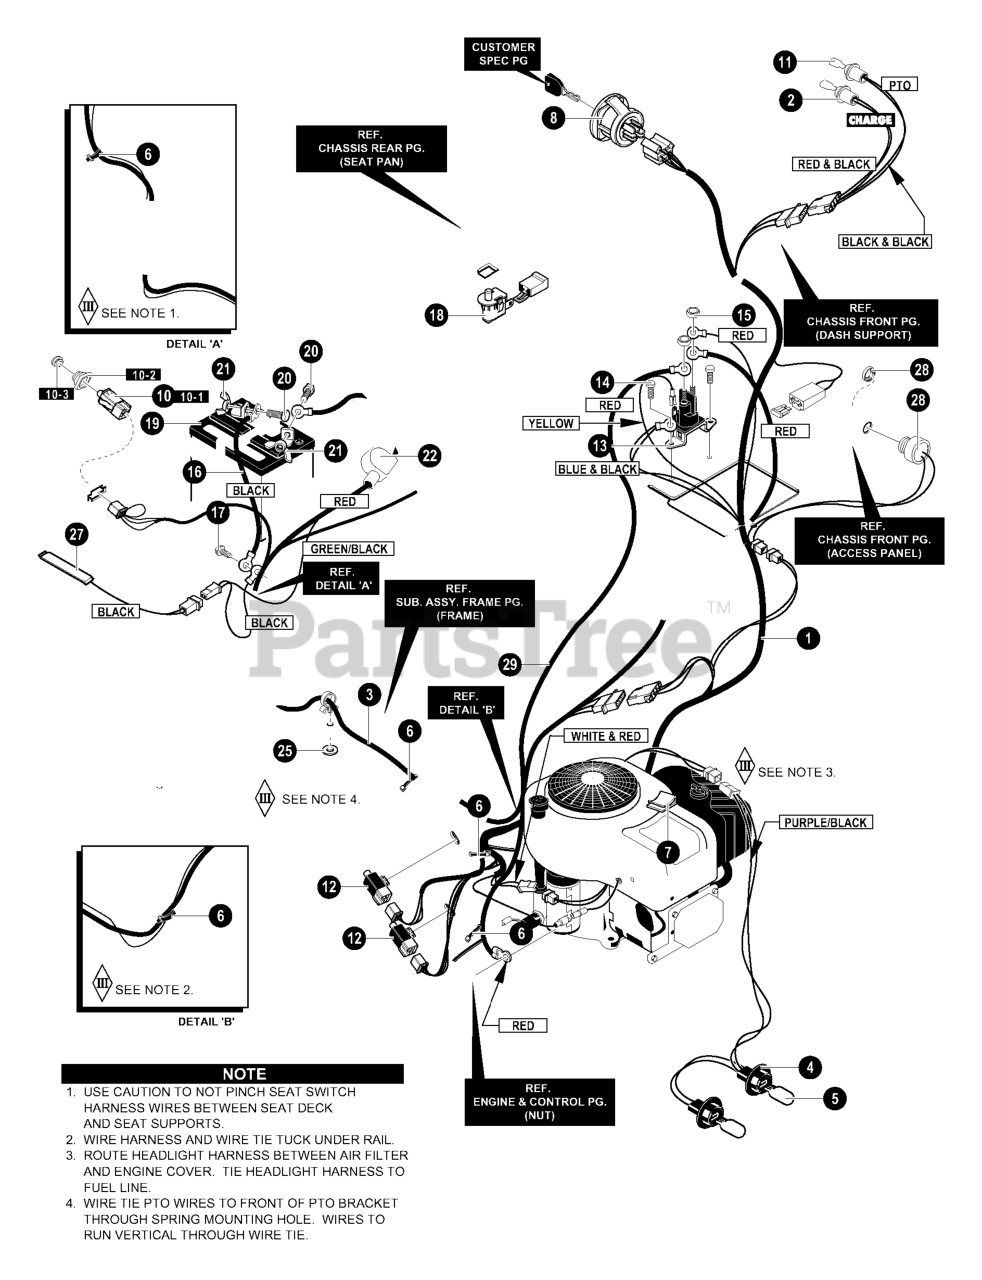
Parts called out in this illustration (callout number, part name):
1	WIRE HARNESS
2	INDICATOR HARNESS
3	REAR HARNESS
4	WIRE HARNESS FOR HEADLIGHTS
5	BULB, HEADLAMP
6	TIE, CABLE BLACK NYLON 5.62L
7	WIRE CLIP, ADHESIVE
8	SWITCH, IGNITION
10	ASSY, SWITCH DOUBLE POLE DELTA
10-1	SWITCH, DOUBLE
10-2	BOOT, SWITCH
10-3	SWITCH CAP
11	BULB, INDICATOR
12	SWITCH LIMIT
13	SOLENOID
14	SCREW, 1/4X.50
15	NUT, 1/4-20 HEXNYL
16	WIRE, GROUND
17	SCREW,1/4X.50
18	SWITCH, SEAT
19	BATTERY 5 PLATE MAINT FREE
20	BOLT,1/4-20X.63
21	NUT, WING 1/4-20
22	BOOT, BATTERY
25	WASHER, FLAT .250X56X.0478
27	TAPE SWITCH
28	BUZZER, FOR BAG FULL
29	WIRE, LEAD SOLENOID TO STARTER
